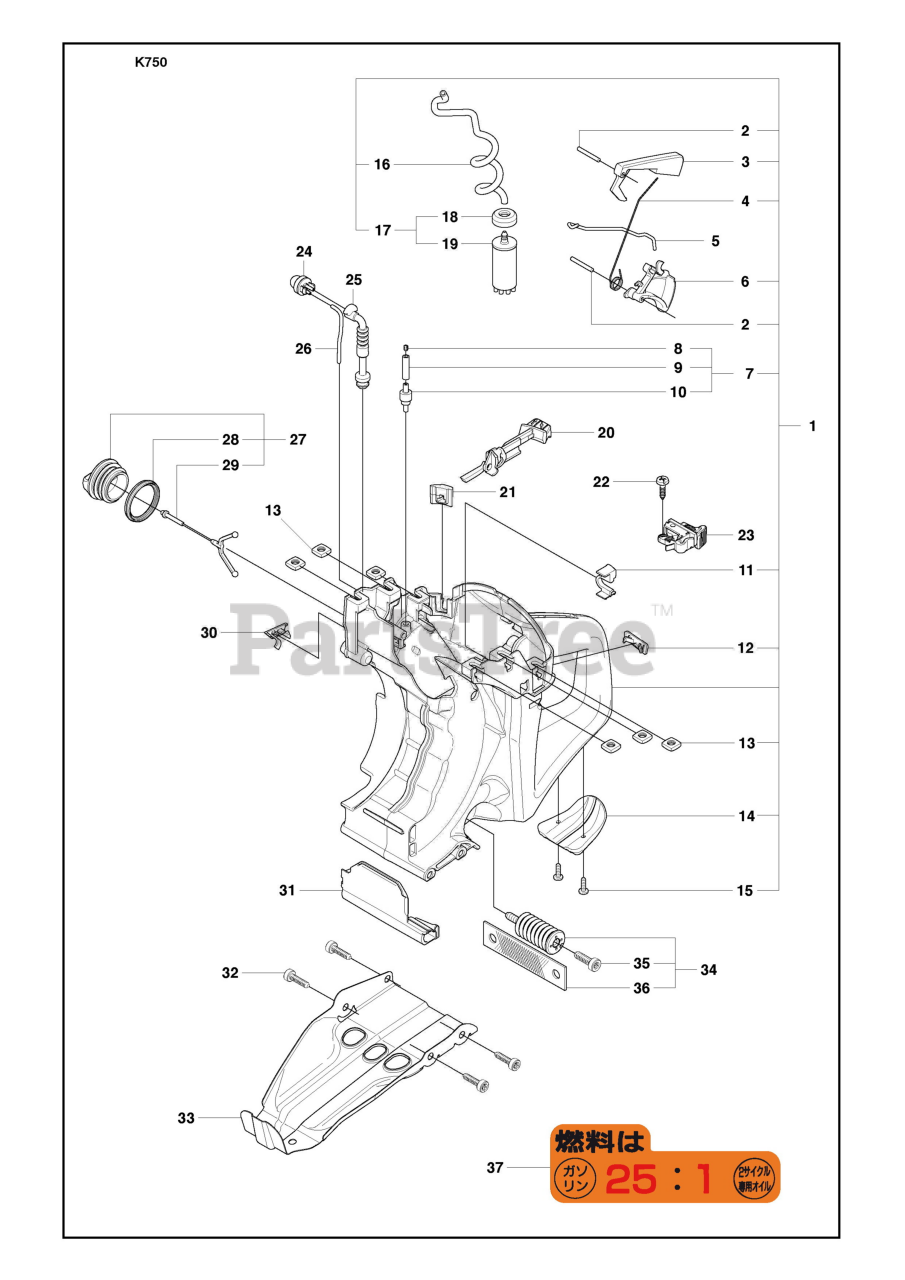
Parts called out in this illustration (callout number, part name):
1	Fuel Tank
2	Parallel Pin
3	Throttle Lockout
4	Spring
5	Throttle Rod
6	Throttle Trigger
7	Tank Vent Assy
8	Sinter Plug
14	Ground Support
16	Fuel Hose
17	Fuel Filter
18	Hose Clamp
19	Fuel Filter
20	Choke Control
23	Stop Switch
24	Primer Housing
25	Fuel Hose
26	Fuel Hose
27	Tank Cap Assy
29	Tank Cap Holder
31	Heat Shield
33	Base Plate
34	Vibration Absorber
37	Label
